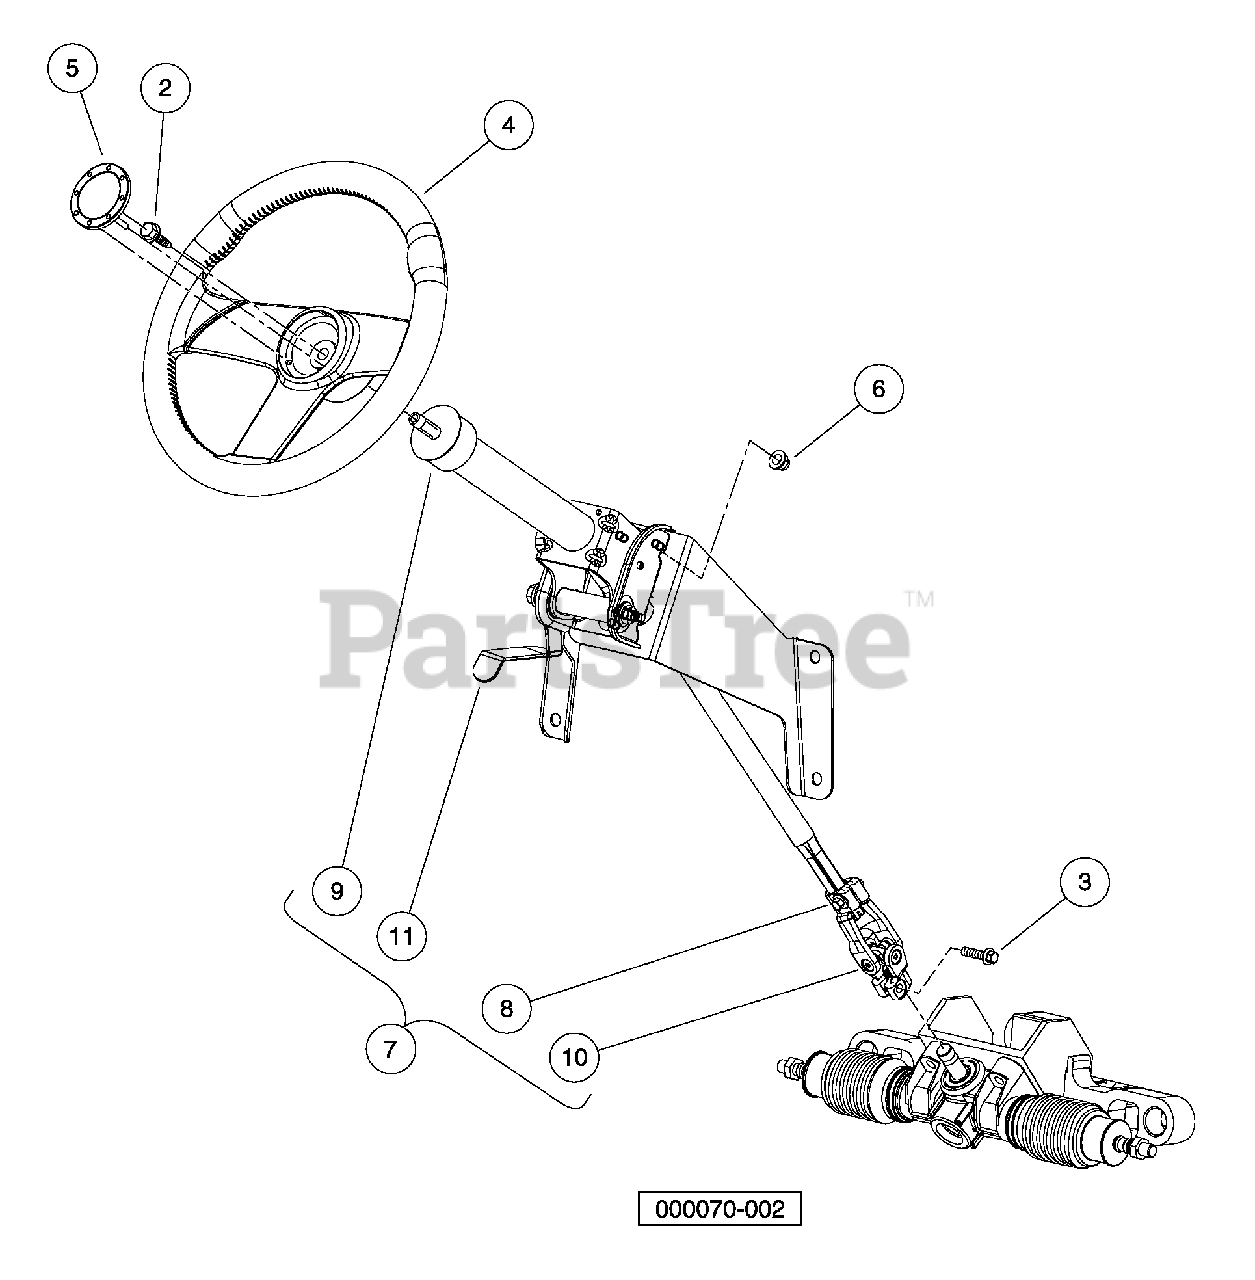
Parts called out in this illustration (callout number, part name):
1	Instl, Steering System
2	Bolt, M10 X 20 Hex Washer Hd
3	Bolt, Flange Head, M8 X 30.0
4	Steering Wheel, Viper, Hex Hub
5	Cap, Steering Wheel, Viper
6	Lock Nut, Flg M8 X 1.25 Nylon
7	Steering Column
8	Bolt, Flange Head, M8 X 30.0
9	Shroud, Steering Column
10	Bolt, M4 X .7 X 60
11	Handle, Steering, Tilt
